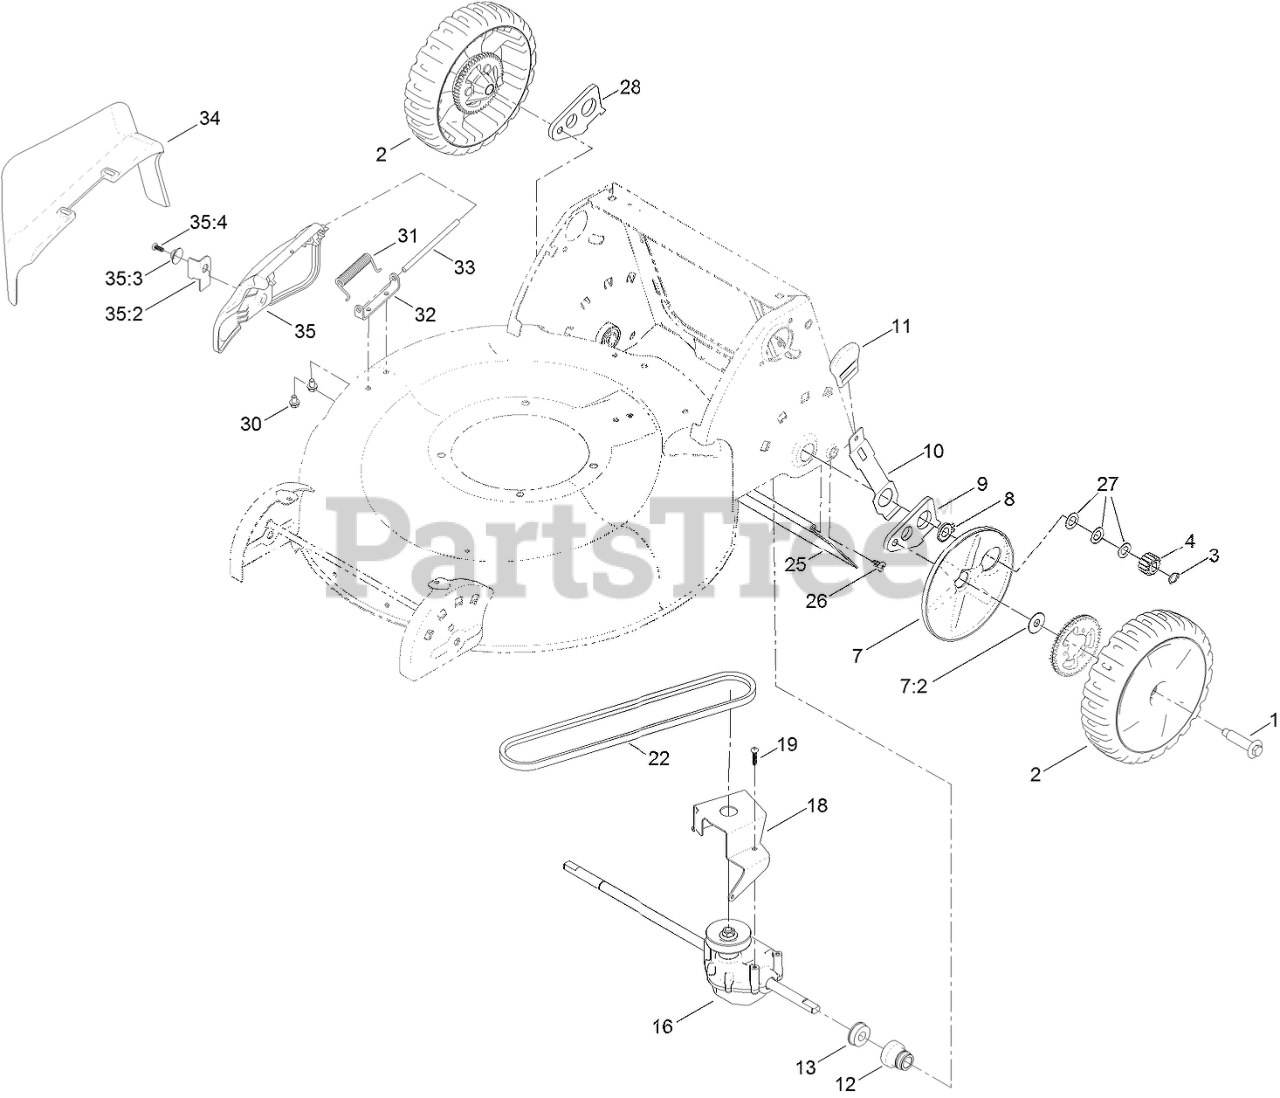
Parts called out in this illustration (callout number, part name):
1	BOLT-SHOULDER
2	8 INCH WHEEL AND GEAR ASM
3	RING-RETAINING
4	GEAR-PINION, 15T
7	WHEEL COVER ASM
7:2	WASHER-STEPPED
8	RING-RETAINING
9	ARM-REAR PIVOT, LH
10	ARM-SPRING, REAR
11	KNOB-HOC
12	RETAINER-BEARING, HOC
13	BEARING-BALL
16	TRANSMISSION-INSIGHT SAS
18	BRACKET-TRANSMISSION
19	SCREW-PLASTITE
22	V-BELT
25	SHIELD-TRAILING
26	SCREW-PTH
27	WASHER-PLAIN
28	ARM-REAR PIVOT, RH
30	SCREW-HWH
31	SPRING-TORSION
32	BRACKET-COVER
33	ROD-COVER
34	CHUTE-DISCHARGE, SIDE
35	DISCHARGE DOOR ASM
35:2	LATCH-DOOR
35:3	CAP-DOOR
35:4	SCREW-PLASTITE
